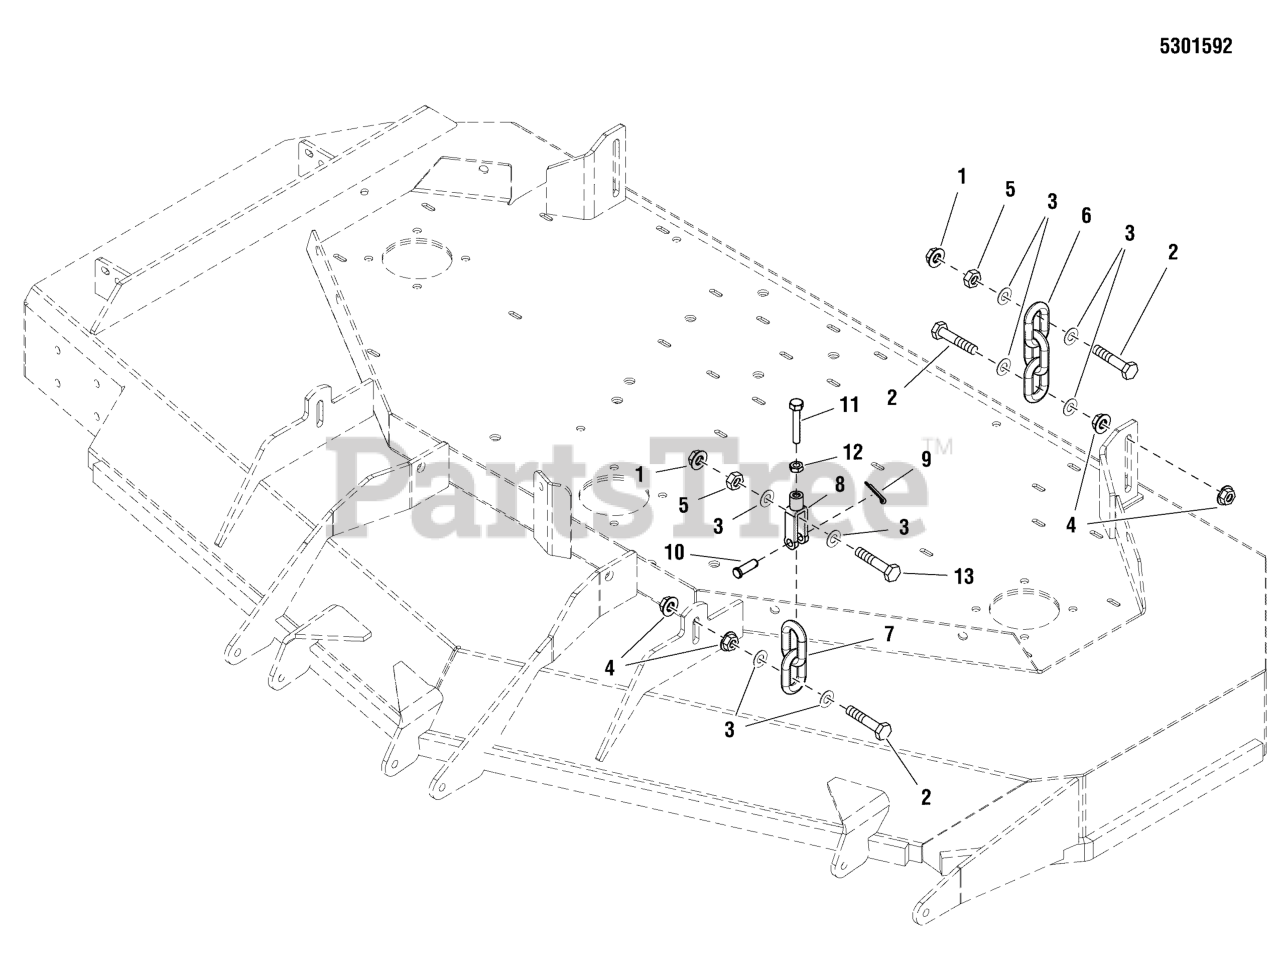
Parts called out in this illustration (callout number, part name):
1	NUT, 3/8-16 HEX NYLON LOCK
2	BOLT, 3/8-16 X 1-3/4" GD5 CZ
3	WASHER, 3/8 SAE
4	NUT, 3/8-16 HEX SERRATED FLANGE
5	NUT, 3/8-16 HEX JAM
6	CHAIN, 5/16 GD30, 3 LINKS
7	HANGER, FRONT DECK - 2 LINK
8	CLEVIS, 5/16-18, 3/8 PIN HOLE
9	PIN, CLEVIS, 3/8 X 1-1/8
10	PIN, COTTER, 1/8 X 3/4
11	BOLT, 5/16-18 X 2 GD5 TFL
12	NUT, 5/16-18 HEX JAM
13	BOLT, 3/8-16 X 2, GD5, CZ
